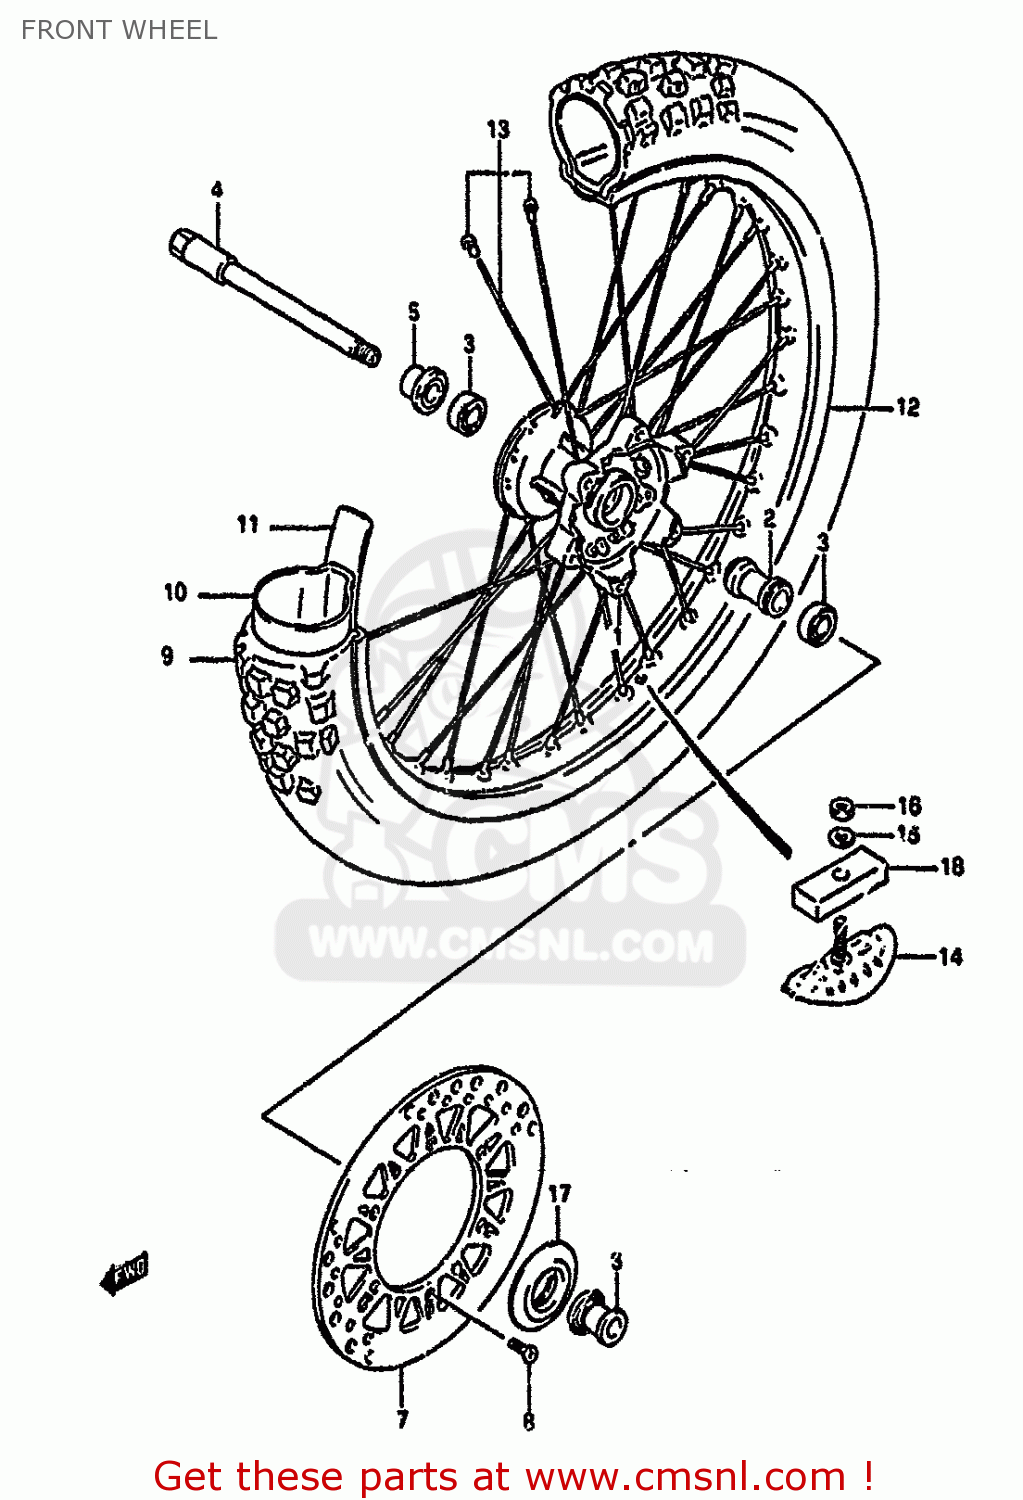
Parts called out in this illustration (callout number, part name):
1	HUB,FRONT
2	SPACER,FR HUB BEARING
3	BEARING
4	AXLE,FRONT
5	SPACER,FR AXLE,R
6	SPACER,FRONT AXLE,LEFT
7	DISC,BRAKE
8	SCREW
9	TIRE,FRONT (80/100-21) (DUNLOP)
10	TUBE,INNER
11	PROTECTOR,WHEEL INNER
12	RIM,FRONT WHEEL (1.60X2
13	SPOKE SET,FRONT
14	STOPPER,BEAD
15	WASHER
16	NUT
17	CAP,FR HUB,L
18	CUSHION,BEAD STOPPER
